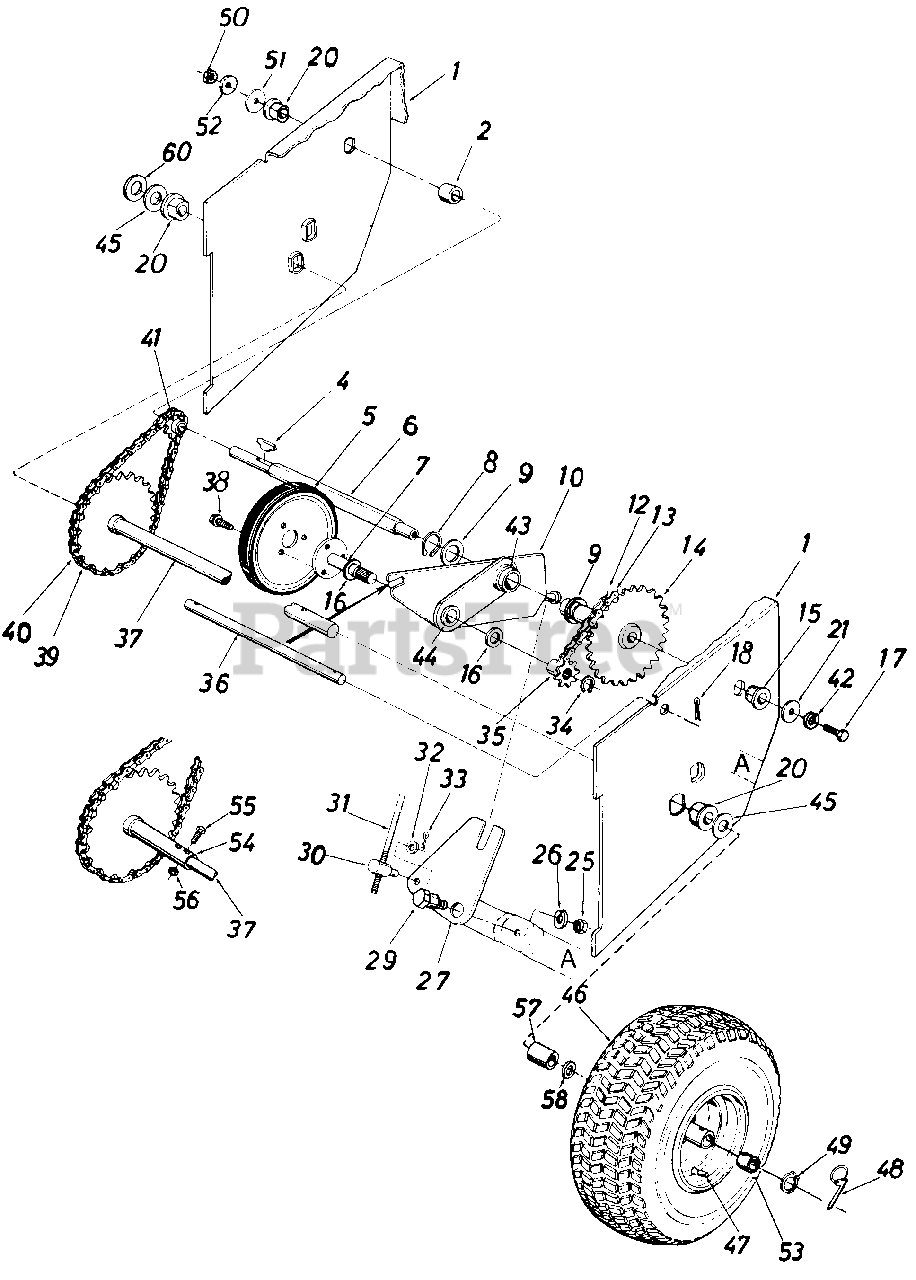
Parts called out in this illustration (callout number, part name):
1	Frame Ass'y.
2	Spacer .50" I.D. x .75" O.D. x.78" Lg.
4	#4 Hi-Pro Key 3/32 x 518" Dia.
5	Friction Wheel Ass'y.
7	Friction Wheel Mounting Plate Ass'y.
8	Snap Ring 1.00" Dia. Shaft
9	Fl-Wash. 1.00" x 1.63" O.D. x .03
10	Sliding Bracket Ass'y.
12	#41 Chain 1/2" Pitch x 35 Links
13	Master Link for #41 Chain
14	32 Teeth Sprocket Ass'y.
15	Hex Flange Brg. .630" I.D.
16	Fl-Wash. .62" I.D. x 1.00" O.D. x .06
17	Hex Lock Bolt 5/16-18 x .62" Lg.
18	Cotter Pin 3132" Dia. x .75" Lg.
20	Flange Brg. w/Flats .75" I.D.
21	Fl-Wash. .34" I.D. x 1.12" O.D. x .125
25	Hex Jam Nut 3/8-16 Thd.
26	L-Wash. 318" I.D.*
27	Shifting Linkage Bracket
29	Shld. Bolt .625" Dia. x .170" Lg.
30	Adjustment Ferrule
31	Shifting Rod 5/16" Dia. x 32.50" Lg.
32	Fl-Wash. .34" I.D. x .64" O.D. x .06
33	Cotter Pin 3/32" Dia. x .75" Lg.
34	Snap Ring .562" Dia. Shaft
35	Sprocket 7 Teeth x .50" Pitch
36	Shaft .50" Dia. x 9.50" Lg.
37	32 Teeth Wheel Axle Ass'y.
38	Hex Wash. Hd. Self-Tap Scr. 5/16-24 x .50" Lg.
39	#41 Chain 1/2" Pitch x 43 Links
40	Master Link for #41 Chain
41	8 Teeth Center Sprocket
42	L-Wash. 5116" I.D.
43	Bearing
44	Bronze Bearing
45	Fl-Wash. .76" I.D. x 1.49 0 O.D.
46	Wheel Assembly
47	Air Valve
48	Klick Pin
49	Snap Ring .75 Dia.
50	Hex Ins. L-Nut 1/2-20 Thd.
51	Fl-Wash. .53 I.D. x 1.25 O.D. x .10
52	Bell-Wash. .50 I.D. x 1.0 O.D. x .075
53	Sleeve Brg.
54	32 Teeth Sprocket Hub Ass'y.
55	Hex Bolt 1/4-28 x 1.5"*
56	Hex L-Nut 1/4-28 Thd.
57	Spacer
58	Fl-Washer
60	Fl-Washer
